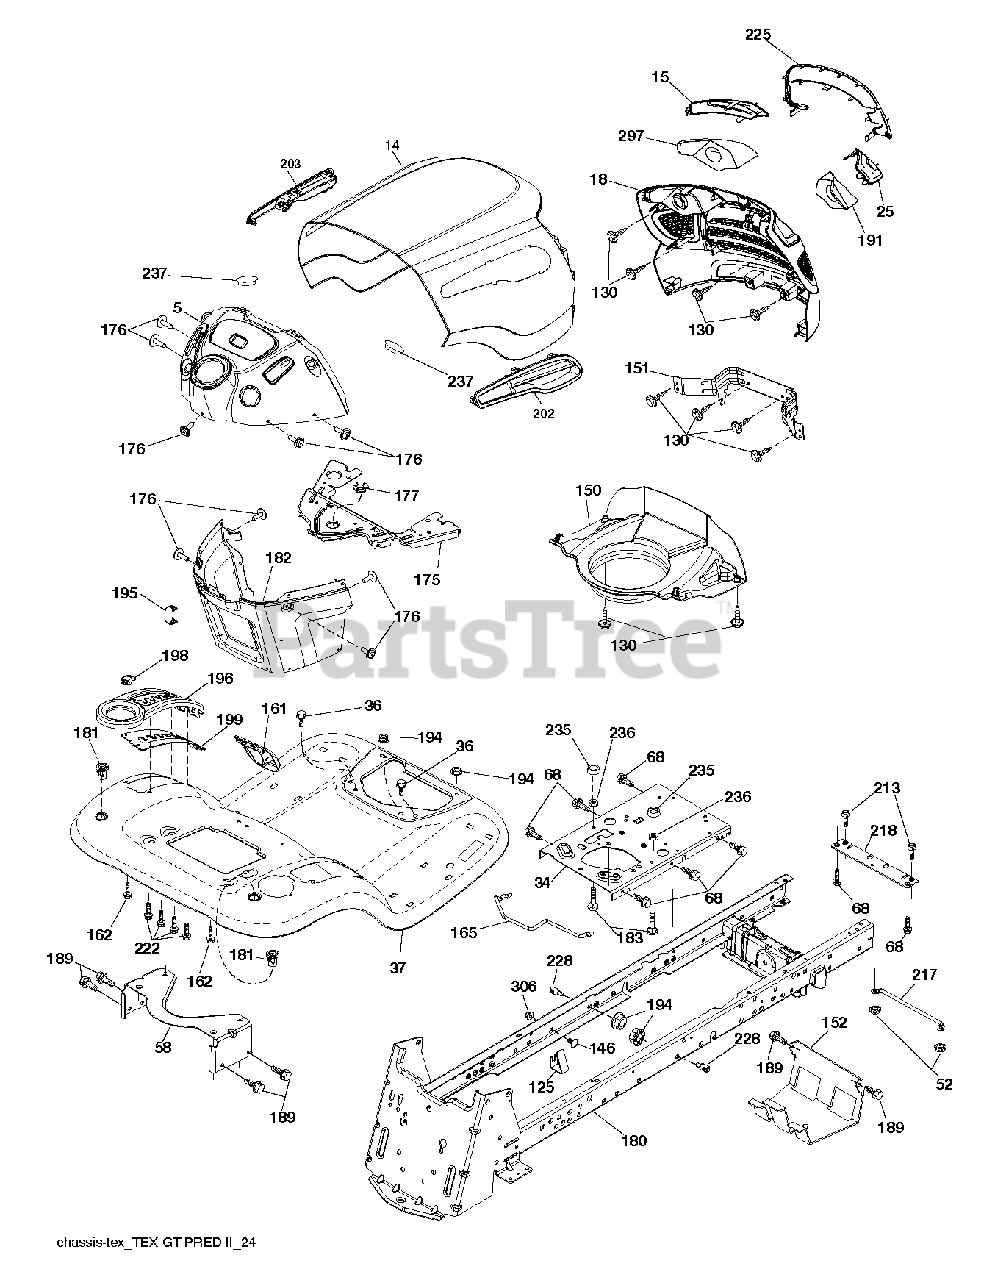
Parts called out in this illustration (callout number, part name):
5	DASH.UPPER.PRED.YT.SQ.CHOKMATC
14	HOOD.PNT.PREDATOR.YT/GT.BLACK
15	Lens, RH Mcculloch GT
18	GRILLE.PREDGT2.GEN
25	LENS.MCCULLOCH.GT.LH
34	PLATE.ENGINE.WELDED.CHASSIS
36	SCREW 5/16"
52	LOCKNUT
58	BRKT.SUPPORT.FNDR/TANK
68	SCREW LT
125	CLIP.FUEL.LINE
130	SCREW.#10 X 0.750.BOS (2 2)
146	BOLT.RDHD.SHT.SQNK.3/8-16X5/8
150	PREDATOR.YT.GT.HOOD.AIR DUCT
151	BRACKET.PIVOT.PREDATOR
152	SHIELD.BROWNING.W/TEX
161	CONSOLE.FUEL.WINDOW.STGT.BLACK
162	SCREW.HI-LO.CONSOLE
165	SUPPORT.TANK.REAR.W/TEX
175	PLATE.CROSSMEMBER.HUSQ
176	SCREW.#10-24X5/8.RN.QU
177	BUSHING STEERING
180	CHASSIS.GT.SLOPED.DRAWBAR.
181	FEND/FTRST.PCH.CPH.NFW
182	DASH LOWER.HUSQ.PRED NO CRUISE
183	BOLT.5/16-18X1-1/4 FULL THD
189	SCREW
191	REFLECTOR.MCCULLOCH.GT.RH
194	NUT LOCK HEX FLANGE 5/16-18
195	PLUG.HOLE.DASH.
199	PLATE DECK LIFT
202	VENT.SIDE.HOOD.LH.PREDATOR.BLK
203	VENT.SIDE.HOOD.RH.PREDATOR.BLK
213	BOLT
217	ROD.PIVOT.HOOD
218	X-PIECE.HOOD.STOP.NON/
222	SCREW.1/4-20X5/8
228	STUD.FASTNER.W/ANTI-ROTATE
235	SPACER FENDER
236	NUT.CENTERLOCK.5/16-
237	PLUG.MOUNT.CARGO.BLK
297	REFLECTOR.MCCULLOCH.GT.RH
306	NUT LOCK FLG 3/8-16 UNC
